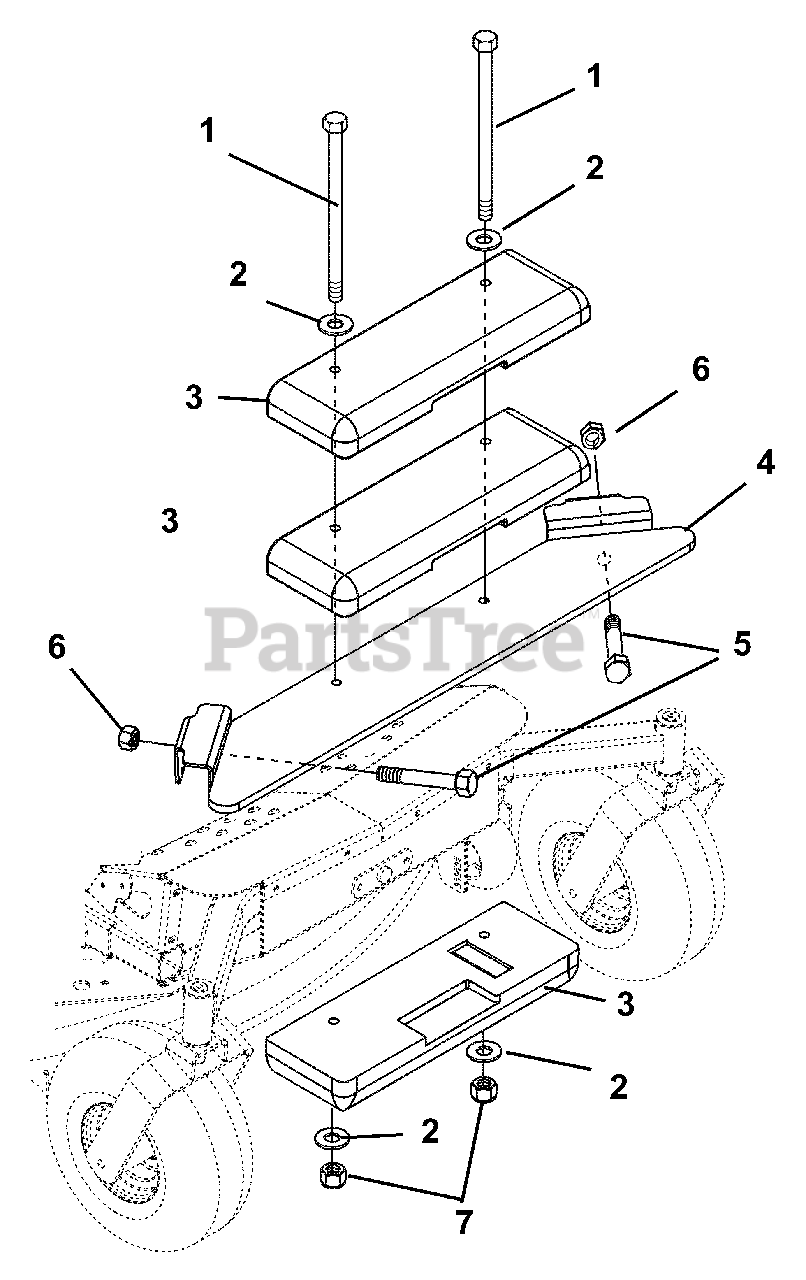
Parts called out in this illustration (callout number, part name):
1	Bolt-Hex .50-13 x 7.50 Grade 5
2	Washer-Flat-Steel .51 x 1.00 x .062
3	Weight
4	Weldment-260Z Counter Weight
5	Bolt-Hex .38-16 x 3.00 Grade 5
6	Nut-Locking-Nylon .38-16
7	Nut-Locking-Center .50-13
